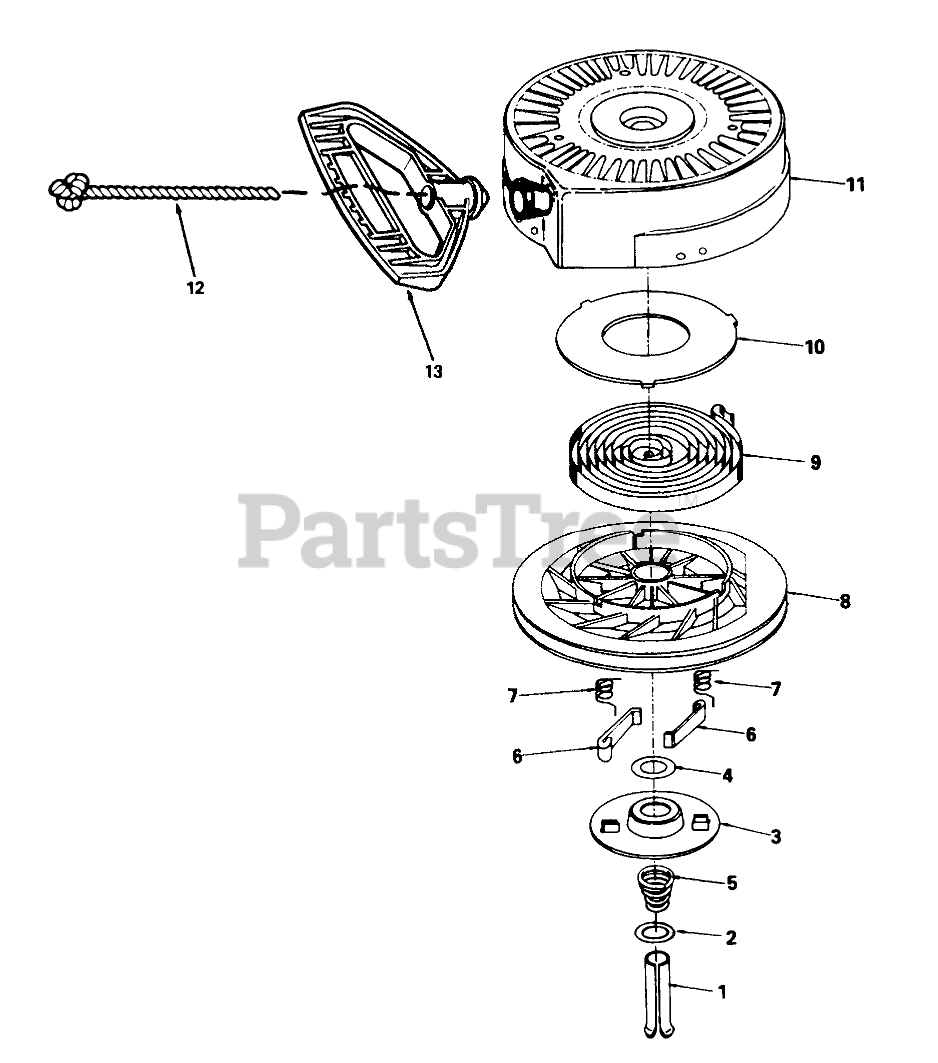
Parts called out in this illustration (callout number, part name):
1	Pin-Spring (Incl Ref. #4)
3	Retainer
5	Brake Spring
6	Dog-Starter
7	Spring-Dog
8	Pulley and Rewind Spring ASM
9	Rewind Spring
10	Cover-Spring
11	Housing Assembly
12	Rope-Starter (98 cut to length)
13	Handle-Starter, Mitten Grip
